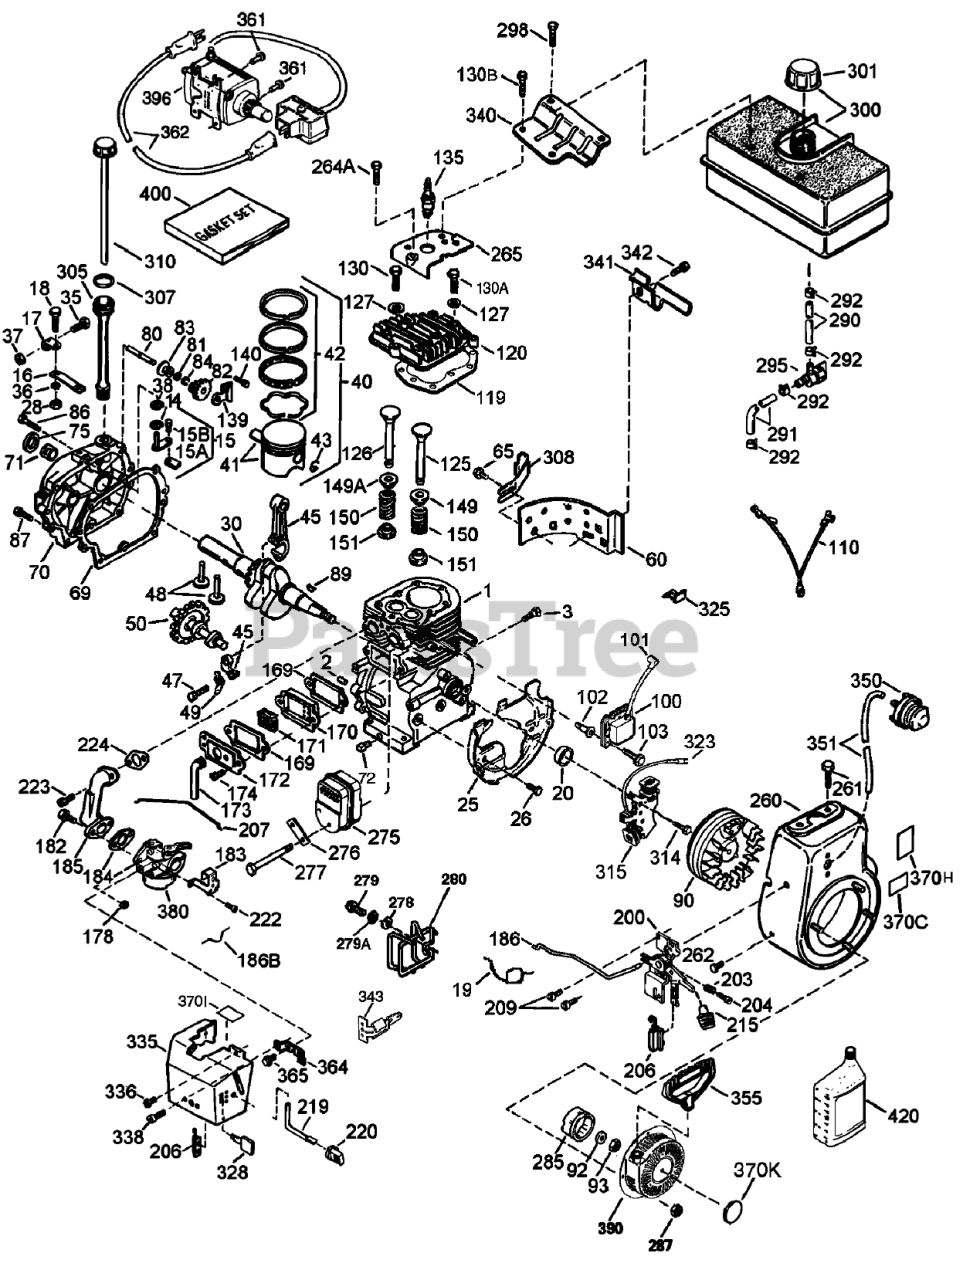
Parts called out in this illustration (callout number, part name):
1	Cylinder ASM (Incl. Ref. # 2, 20 and 72)
2	Pin-Dowel
3	Screw (1/4-20x1/2)
14	Washer-Flat
15	Rod-Governor (Incl. Ref. # 15A and 15B)
15A	Yoke-Governor
15B	Screw (6-40x5/16)
16	Lever-Governor
17	Clamp-Lever, Governor
18	Screw (T-15, 8-32x7/16)
19	Spring-Throttle
20	Seal-Oil
25	Baffle-Housing, Blower
26	Screw (1/4-20x19/32)
28	Nut-Lock
30	Crankshaft
35	Screw
36	Washer-Lock
37	Nut-Lock
38	Ring-Retaining
40	Piston-Pin and Ring Set (STD)
40	Piston- Pin and Ring Set (.010 O S)
41	Piston and Pin ASM (Std.) (Incl. Ref. #43)
41	Piston and Pin ASM (.010" OS) (Incl. Ref. #43)
42	Ring Set (STD)
42	Ring Set (.010 O S)
43	Ring-Retaining, Piston Pin
45	Connecting Rod ASM. (Incl. Ref. # 47 and 49)
47	Bolt-Rod, Connecting
48	Lifter-Valve
49	Dipper-Oil
50	Camshaft (MCR)
60	Extension-Housing, Blower
65	Screw
69	Gasket-Cover, Cylinder
70	Cylinder Cover (Incl. Ref. # 71, 75, 80-84)
71	Bushing-Crankshaft
72	Plug-Drain, Oil (SQH 1/4-18)
75	Seal-Oil
80	Shaft-Governor
81	Washer
82	Governor Gear ASM (Incl. Ref. # 81)
83	Spool-Governor
84	Ring-Retaining
86	Screw (1/4-20x1-3/16)
87	Screw (1/4-20x1-11/16)
89	Key-Flywheel
90	Flywheel ASM
92	Washer-Belleville
93	Nut-Flywheel
100	Solid State Ignition (Incl. Ref. # 101)
101	Cover-Spark Plug
102	Stud-Mounting, Solid State
103	Screw (T-15, 10-24 x 15/16)
110	Wire-Ground
119	Gasket-Head, Cylinder
120	Head-Cylinder
125	Exhaust Valve (Std.) (Incl. Ref. # 151)
125	Exhaust Valve (1/32" OS) (Incl. Ref. #151)
126	Intake Valve (Std.) (Incl. Ref. # 151)
127	Washer-Flat
130	Screw (5/16-18x1-1/2)
130A	Screw (5/16-18x1-25/32)
130B	Screw (5/16-18x39/64)
135	Spark Plug-Resistor (R J19 L M)
139	Bracket-Gear, Governor
140	Screw (10-24x1/2)
149	Cap-Spring, Valve
149A	Cap-Spring, Valve
150	Spring-Valve
151	Keeper-Spring, Valve
169	Gasket-Cover, Valve
170	Body-Breather
171	Element-Breather
172	Cover-Valve
173	Tube-Breather
174	Screw
178	Nut and Lock Washer (1/4-28)
182	Screw (1/4-28x1)
183	Bracket-Choke
184	Gasket-Carburetor To Intake Pipe
185	Pipe-Intake
186	Link-Governor
186B	Spring-Choke
200	Control Bracket (Incl. Ref. # 19, 203, 204 and 206)
